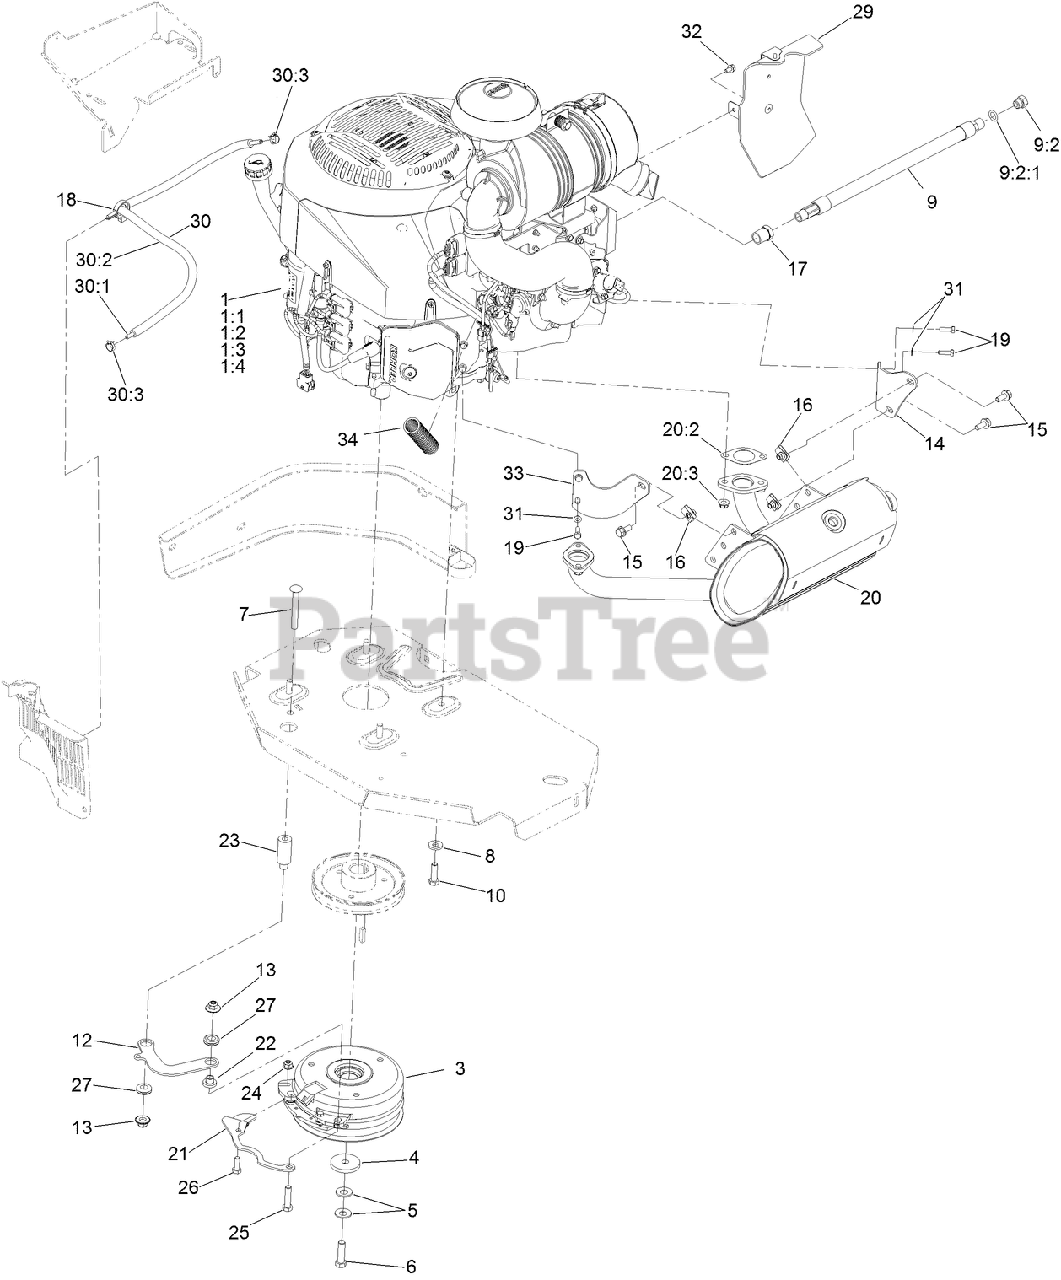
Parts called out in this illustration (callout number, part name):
1:1	KOHLER 52 050 02-S ENGINE OIL FILTER
1:2	KOHLER 25 083 01-S ENGINE AIR FILTER
1:3	KOHLER 25 083 04-S SAFETY FILTER
1:4	KOHLER 25 050 42-S FUEL FILTER
3	CLUTCH, CMS250
3	CLUTCH KIT
4	WASHER-CLUTCH
5	WASHER-SPRING
6	SCREW-HH, W/LOCTITE
7	SCREW-CARR
8	WASHER-BELLEVILLE
9	OIL DRAIN HOSE ASM
9:2	PLUG-HH
9:2:1	O-RING
10	SCREW-HH
12	LINK-ANCHOR, CLUTCH
13	NUT-FLANGE, NI
14	BRACKET-MUFFLER
15	SCREW-HH
16	NUT-U
17	BUSHING
18	CLAMP-HOSE
19	SCREW-HH
20	MUFFLER-940-980 KOH EFI
20	MUFFLER KIT
20:2	GASKET-EXHAUST
20:3	NUT-FLANGE, LOCK
21	BELT-GUIDE
22	SPACER
23	SPACER
24	NUT-HF, NI
25	SCREW-HH
26	SCREW-HH
27	GROMMET-RUBBER
29	REAR BAFFLE ASM
30	FUEL LINE ASM
30:1	HOSE-FUEL
30:2	SLEEVE, THERMAL
30:3	CLAMP-HOSE
31	WASHER-SPRING
32	SCREW-HWH
33	BRACKET-MUFFLER, FRONT
34	CONDUIT-CONVOLUTED
